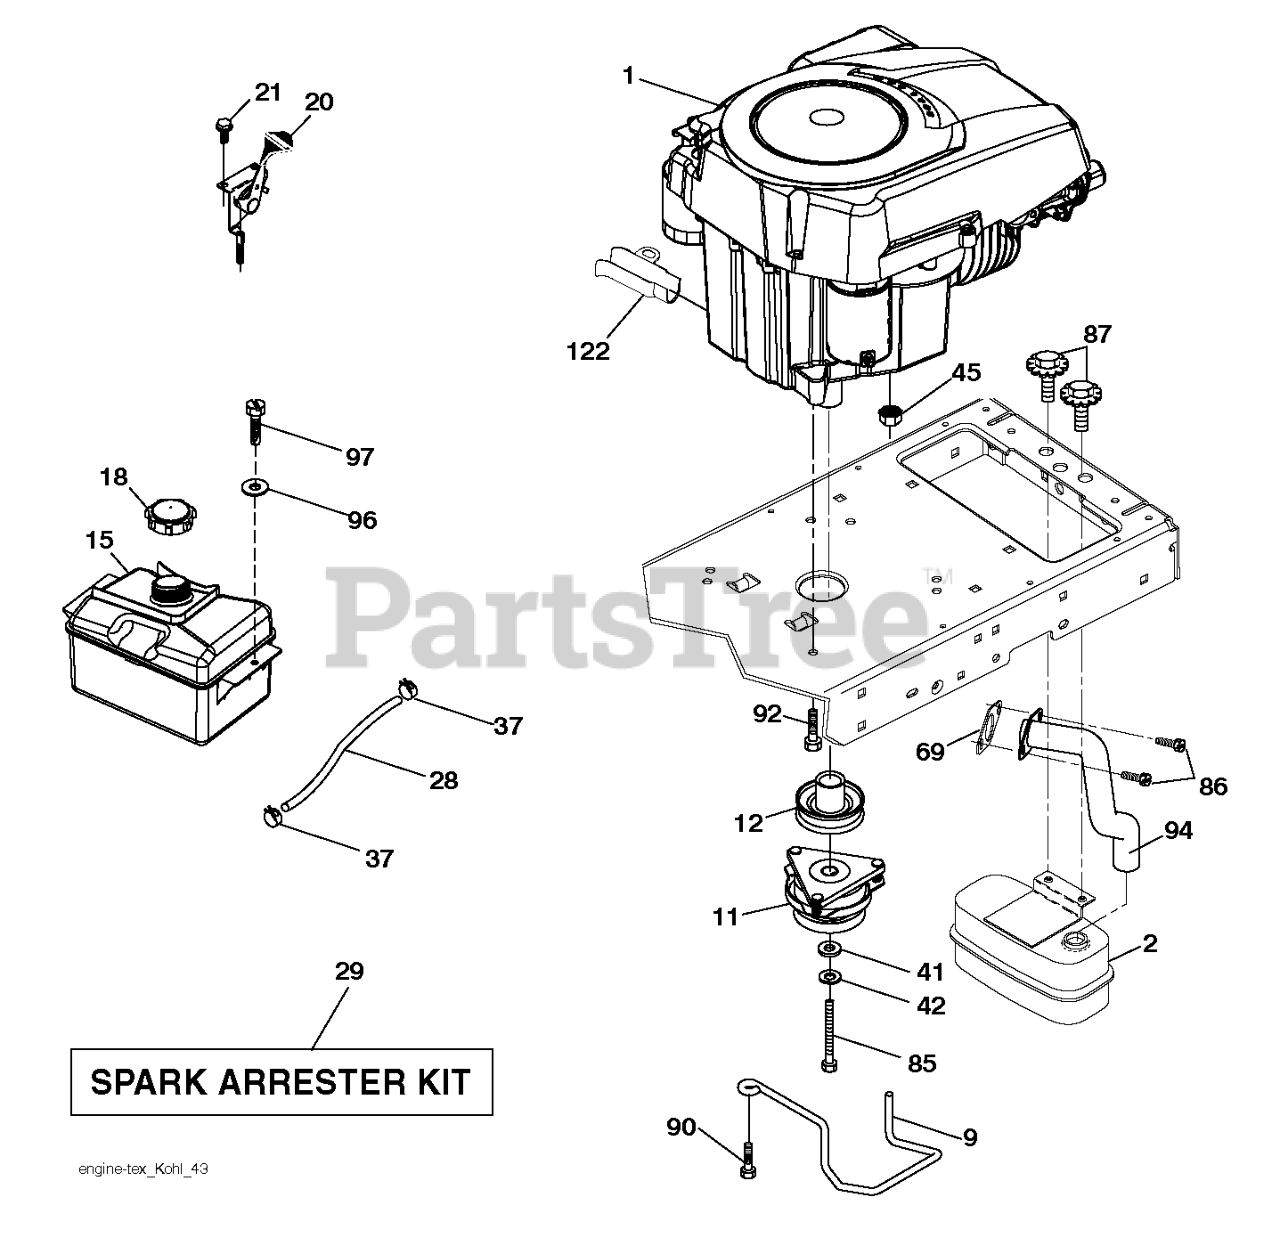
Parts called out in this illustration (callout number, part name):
2	MUFFLER.SINGLE.CYL.KOHL/B&S
9	KEEPER.BELT.ENGINE.4.2
11	CLUTCH.ELECTRIC.LT.48"*
12	PULLEY.ENGINE.TUFFTORQ
15	RP TANK FUEL FRT 1.5 GAL
18	CAP ASM.FUEL.2.25"FR.
20	CONTROL.TH/CK.C.
21	SCREW.#10 X 0.750.BOS
28	LINE.FUEL.20
29	KIT.SPARK ARRESTOR 794945 B&S
37	HOSE CLAMP
42	LOCKWASHER
45	NUT
69	GASKET.EXHAUST.KOHLER
85	BOLT HEX 7/16-20X4-1/4"
86	SCREW.SOCKET HD.5/16-1
87	BOLT.5/16-18UNCX3/4 W/SEMS.BLK
90	SCREW 3/8-16X1
92	SCREW 3/8-16X1
94	RP.TUBE.EXHAUST.KOHL.COURAGE
96	WASHER
97	SCREW HEXWSHR 1/4-20X3/4
122	EXTENSION DRAIN OIL
